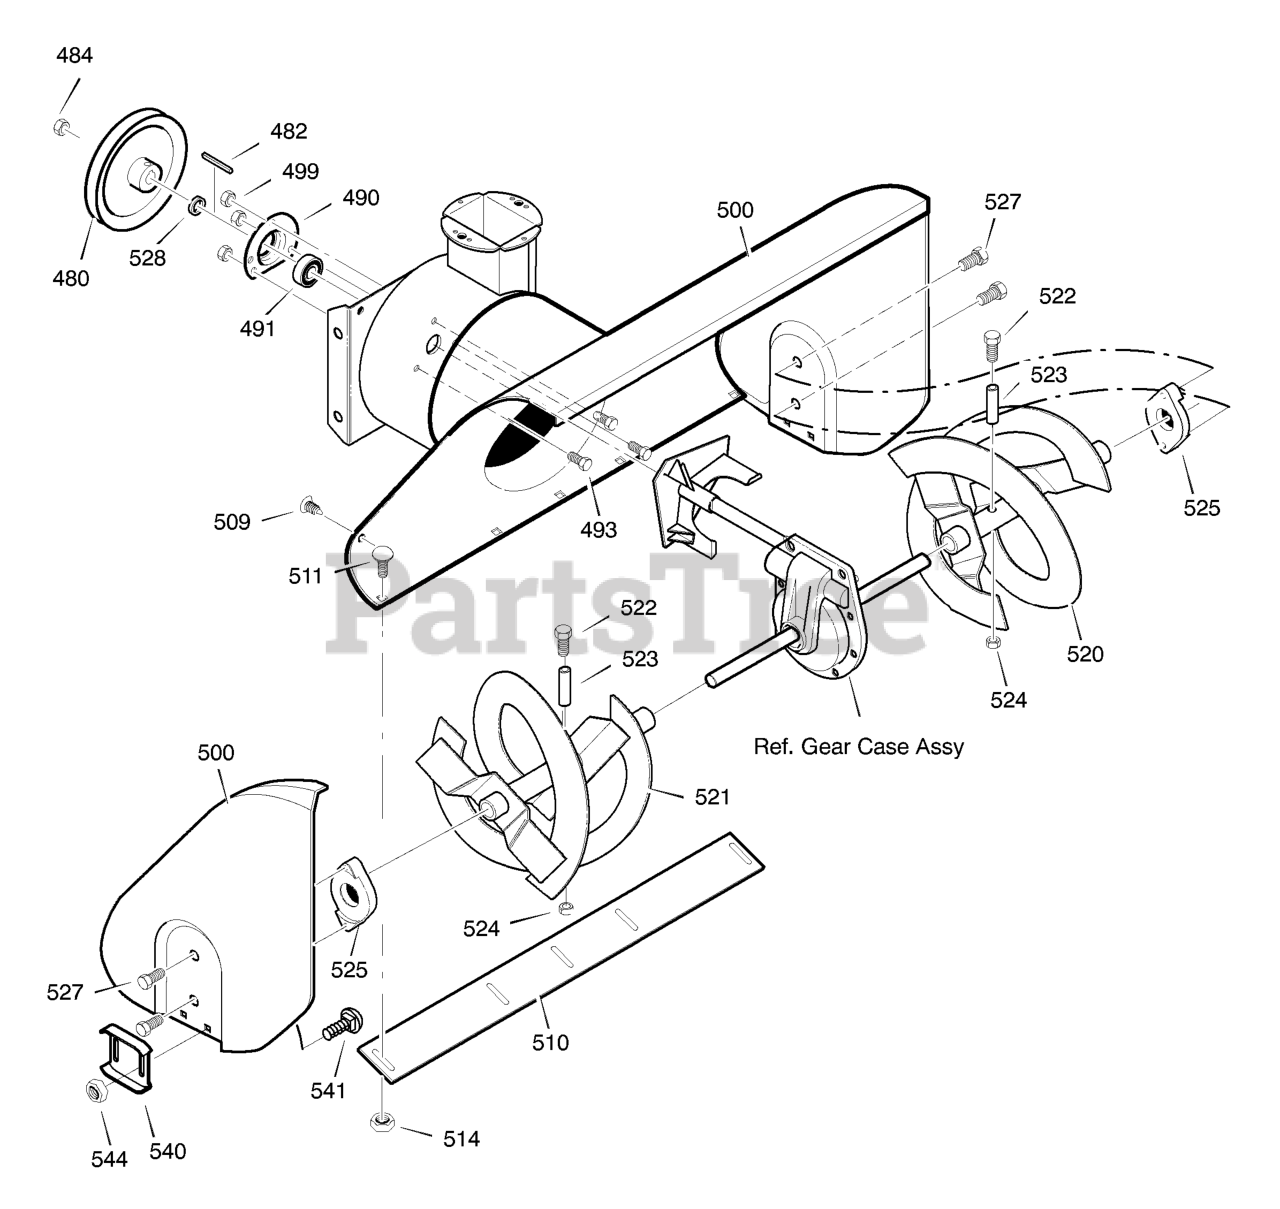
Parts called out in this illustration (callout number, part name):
482	KEY, SQUARE
484	NUT, 1/4-20
485	SPACER, FRICTION PULLEY
490	RETAINER, BALL BRNG
491	BEARING, BALL
493	BOLT, HEX - 0.31-18X0.50
499	NUT, 5/16-18 HEXWDFLLK
500	HOUSING, ASSY
509	PLUG, CHRISTMAS TREE
510	BLADE, SCRAPER
511	BOLT, CARRIAGE
520	AUGER, ASSY, LH
521	AUGER, ASSY, RH
522	BOLT
523	SPACER, SLEEVE
524	NUT, 1/4-20 REGHEXCTRLK
525	BEARING,FLANGE
527	SCREW, 5/16-18 x 0.75
536	BOLT
540	SKID, HEIGHT ADJUST
541	BOLT, 5/16-18 X .75
544	NUT, 5/16-18 REGHEX
